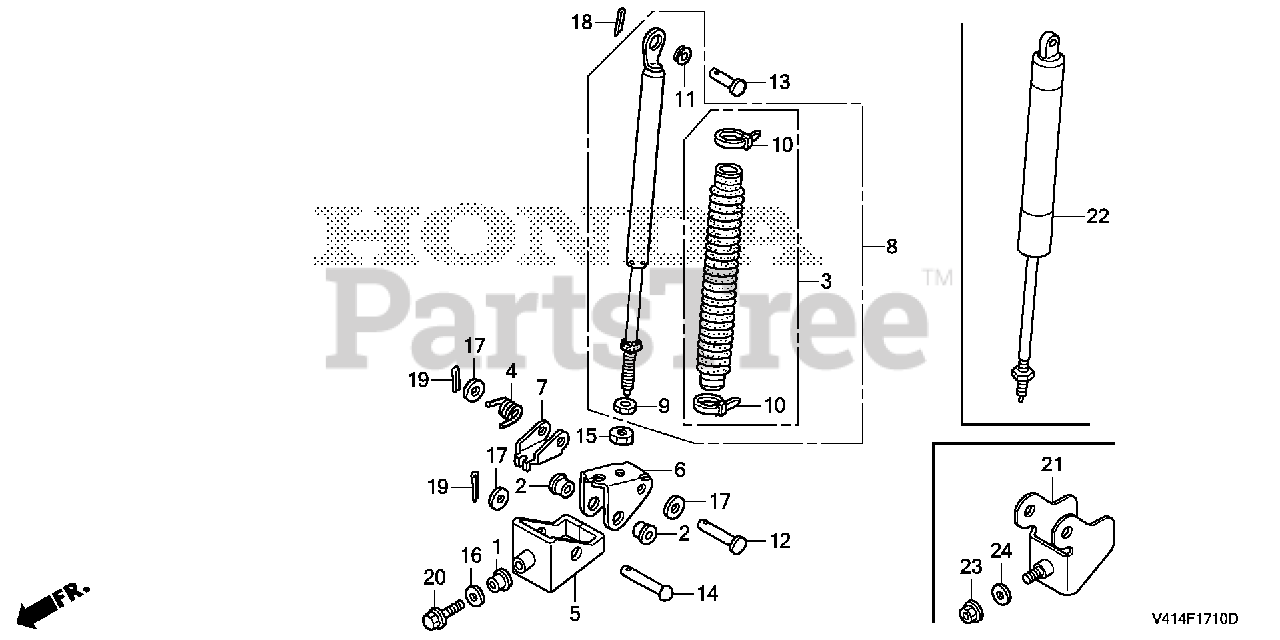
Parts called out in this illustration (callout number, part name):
4	SPRING, HEIGHT ADJUSTING
6	BRACKET, FREE LOCK
7	ARM, PUSH ROD
12	PIN (10X37)
13	PIN (7.2X20)
14	PIN (10X47)
17	WASHER, PLAIN (10MM)
18	PIN, COTTER (2.0X15)
19	PIN, SPLIT (2.5X18)
21	BRACKET, ROLLING
22	LOCK, HEIGHT ADJUSTING FREE
23	NUT, FLANGE (8MM)
24	WASHER, PLAIN (8MM)
